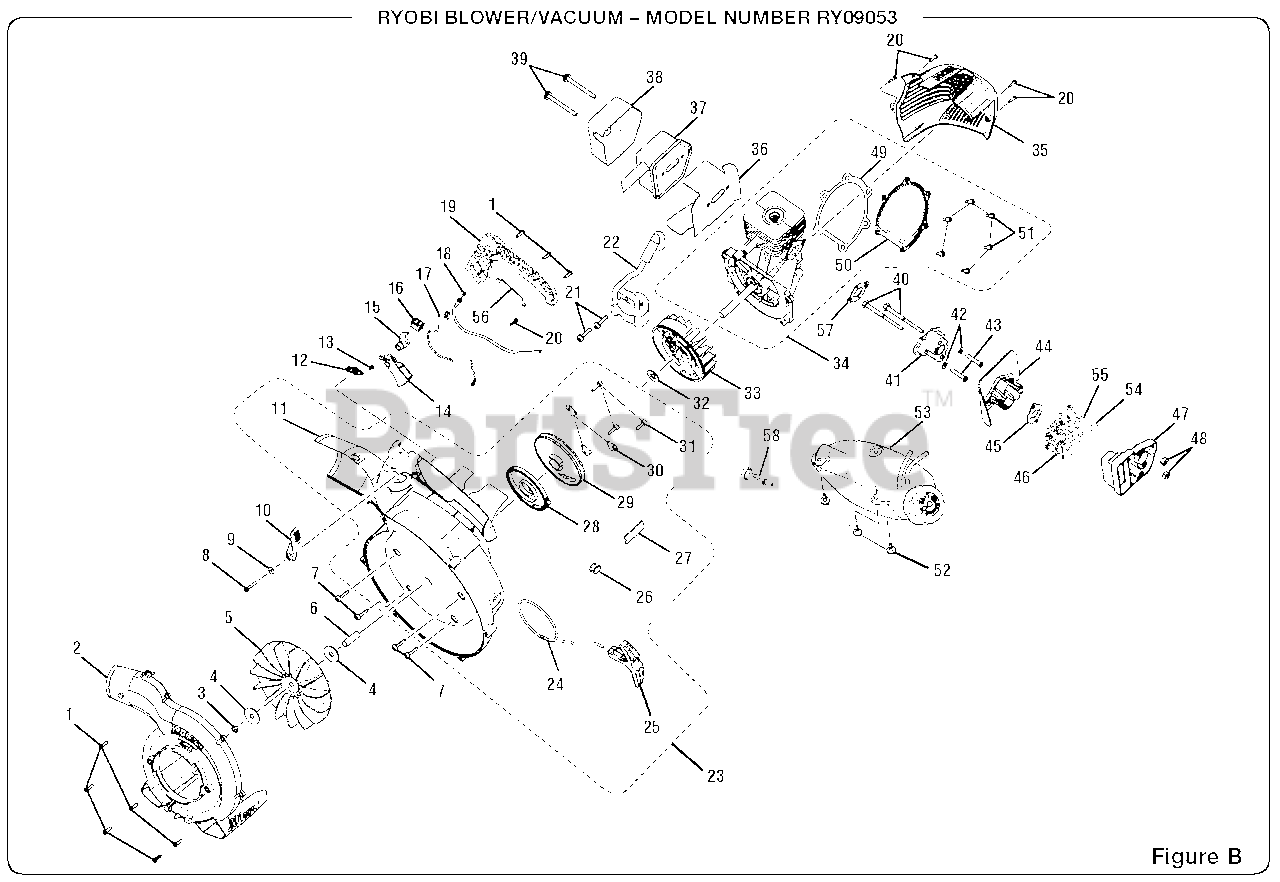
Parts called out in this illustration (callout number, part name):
1	Screw (10-14 x 3/4 in.)
2	Outer Volute
3	Lock Nut (3/8 in.)
5	Fan
7	Screw (M4 x 17 mm, T.F.)
8	Screw (8-14 x 1 in., T.F.)
10	Cruise Lever
11	Lower Housing
12	Throttle Lever
13	Screw (M3.5 x 7.5 mm)
14	Throttle Trigger
15	Trigger Lock
16	Momentary Contact Switch
17	Wire Assembly
18	Throttle Cable
19	Handle Cover
20	Screw (M4 x 18 mm)
21	Screw (M4 x 19 mm, T.F.)
22	Ignition Module
23	Lower Housing w/Starter
24	Starter Rope (42 in.)
25	Starter Grip
28	Spring & Container
29	Starter Pulley
30	Pulley Retainer
31	Screw (M4 x 14 mm, T.F.)
32	Washer
33	Flywheel Assembly
34	Short Block Assembly
35	Engine Cover
36	Muffler Gasket
37	Muffler Assembly
38	Muffler Heat Shield
39	Screw (10-24 x 2-1/8 in.)
40	Screw (10-24 x 2.5 in.)
43	Screw (M5 x 25 mm)
45	Heat Dam Gasket
46	Carburetor
47	Air Box Base
48	Hex Nut (10-24)
49	Crankcase Cover Gasket
50	Crankcase Cover
51	Screw (M4 x 12 mm)
52	Screw (M4 x 14 mm, Shoulder)
53	Fuel Tank Assembly w/Cap
54	Choke Lever
55	Primer Bulb
56	Ground Wire Kit
57	Intake Gasket
58	Fuel Filter
